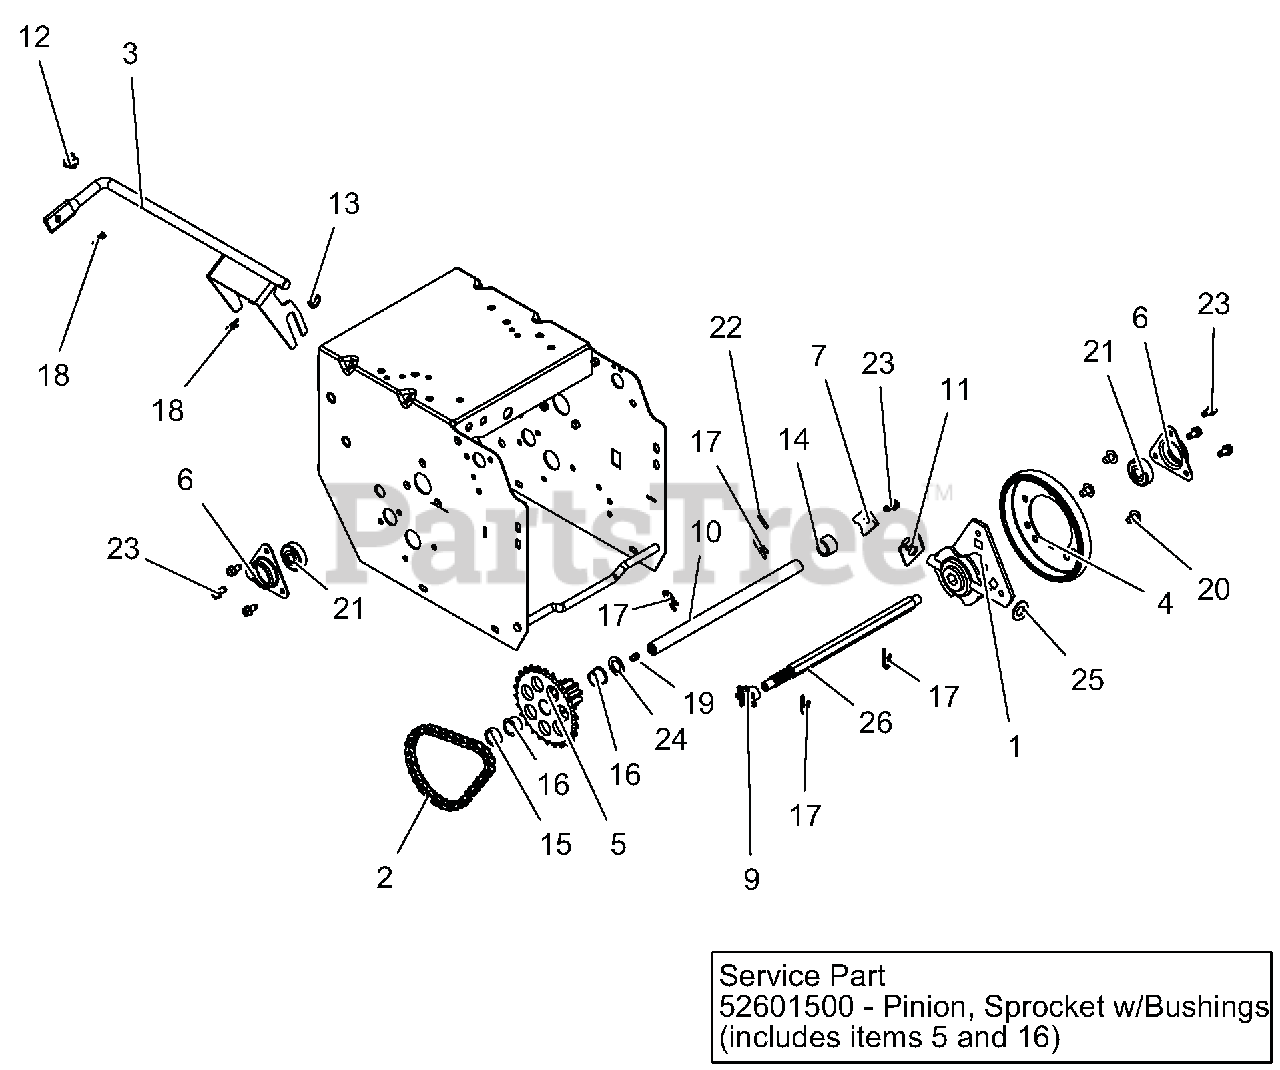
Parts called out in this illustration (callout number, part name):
1	CARRIER, DRIVE DISK
2	CHAIN - #41, 32 PITCHES
3	WELDMENT, SHIFT FORK
4	FRICTION, DISC
5	PINION & SPROCKET
6	FLANGE, BEARING
7	TAB, ANTI ROTATION
9	SPROCKET, PINION 7T W/SPLINE
10	SHAFT, PINION TRACK
11	BRACKET, FORMED - SHIFT FORK
12	BUSHING, POLYLINER-.50 SPLIT
13	BUSHING, POLYLINER-.50 SNAPIN
14	SPACER, .635X.880X.611
15	BSHG-SLV, .635X.880X.305
16	BSHG-FLG .625X.750X.500X.875
17	PIN, SPRING CLIP
18	CLIP, SPRING
19	ZERK,FITTING .25X.125 DRIVE IN
20	SCR-TAP SERRDHDTX .31-18X.50BP
21	BRG-BALL .437X1.375X.437
22	@PIN-GRV .125X1.00 TP E ALLOY
23	SCR-TAP .25-20X.50 HWH TR YWZ
24	WSHR-FL-STL .630X1.005X.062 YZ
25	WSHR-FL-STL .505X1.00X.062YWZC
26	SHAFT, HEX W/SPLINE TRACK
